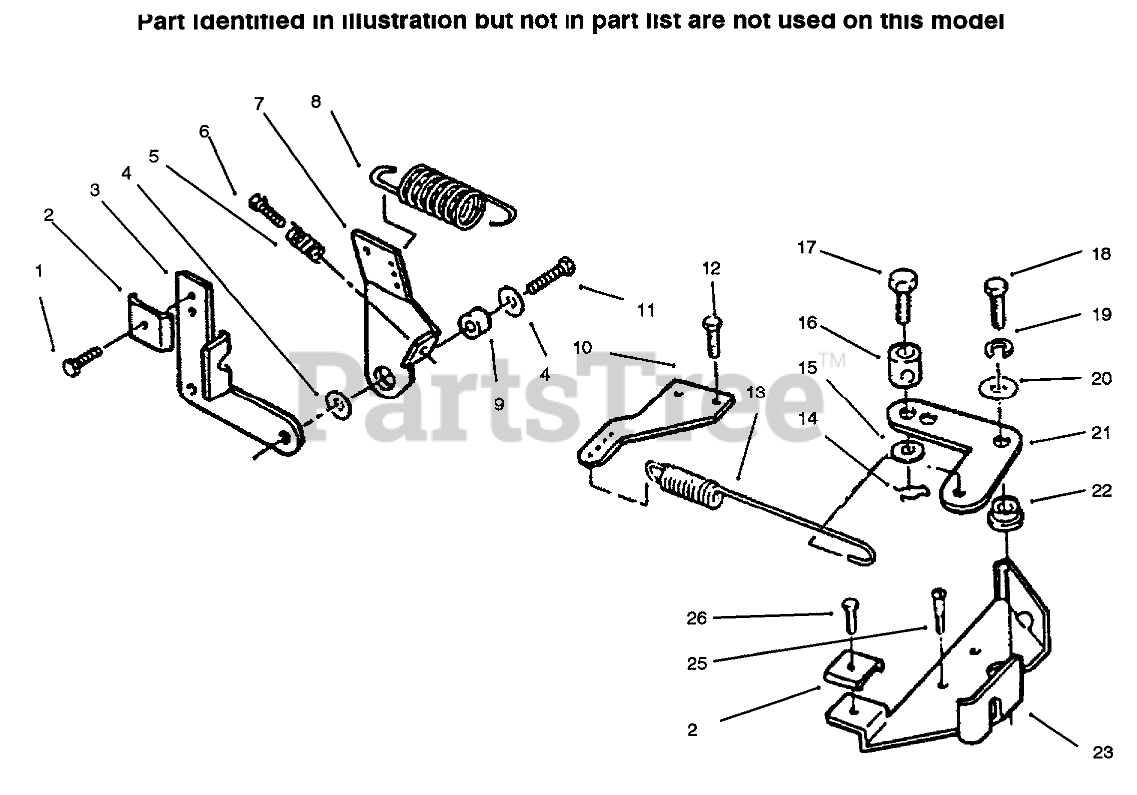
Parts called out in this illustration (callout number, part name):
1	SCREW-TAPPING
3	BRACKET
4	WASHER-FLAT
5	SPRING
6	SCREW-TAP
7	GOVERNOR CONTROL ARM
8	SPRING
9	BUSHING
10	ADAPTER-GOV ARM
11	SCREW-HWH
12	Screw
13	SPRING-GOV
14	PIN-COTTER
15	WASHER-FLAT
16	BUSHING
17	SCREW
18	SCREW - CAP HEX HEAD
19	WASHER-LOCK, SPRING
20	WASHER-FLAT
21	Governor Control Arm
22	BUSHING-GOV CONTROL
23	BRKT-GOVERNOR CONTRL
25	HEX HD CAP SCREW
26	TAPPING HEX HD CS
